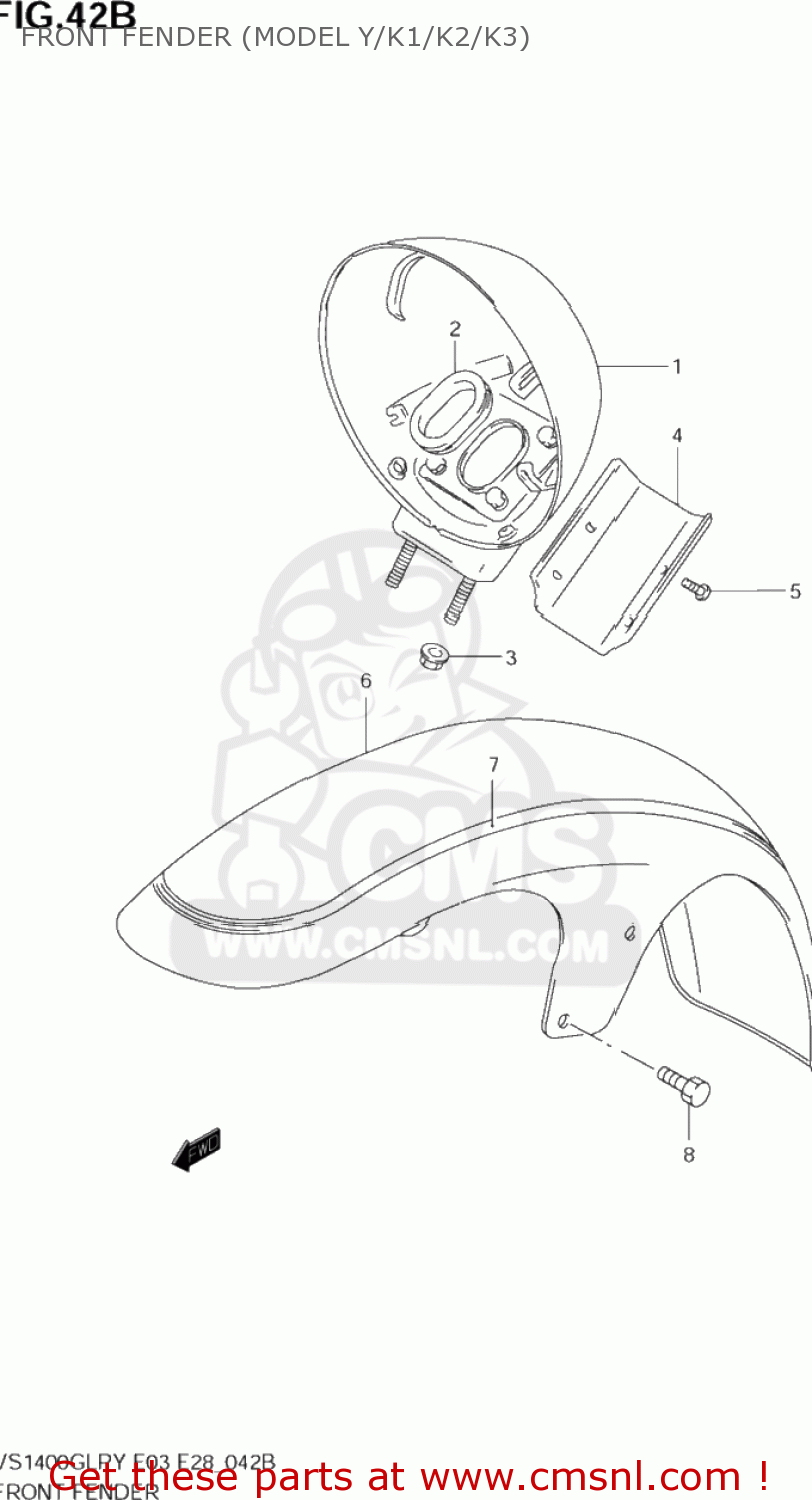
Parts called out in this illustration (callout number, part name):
1	HOUSING,HEADLAMP
2	GROMMET
3	NUT
4	COVER,HEADLAMP HSG
5	SCREW
6	FENDER ASSY,FR
7	TAPE SET
8	BOLT
